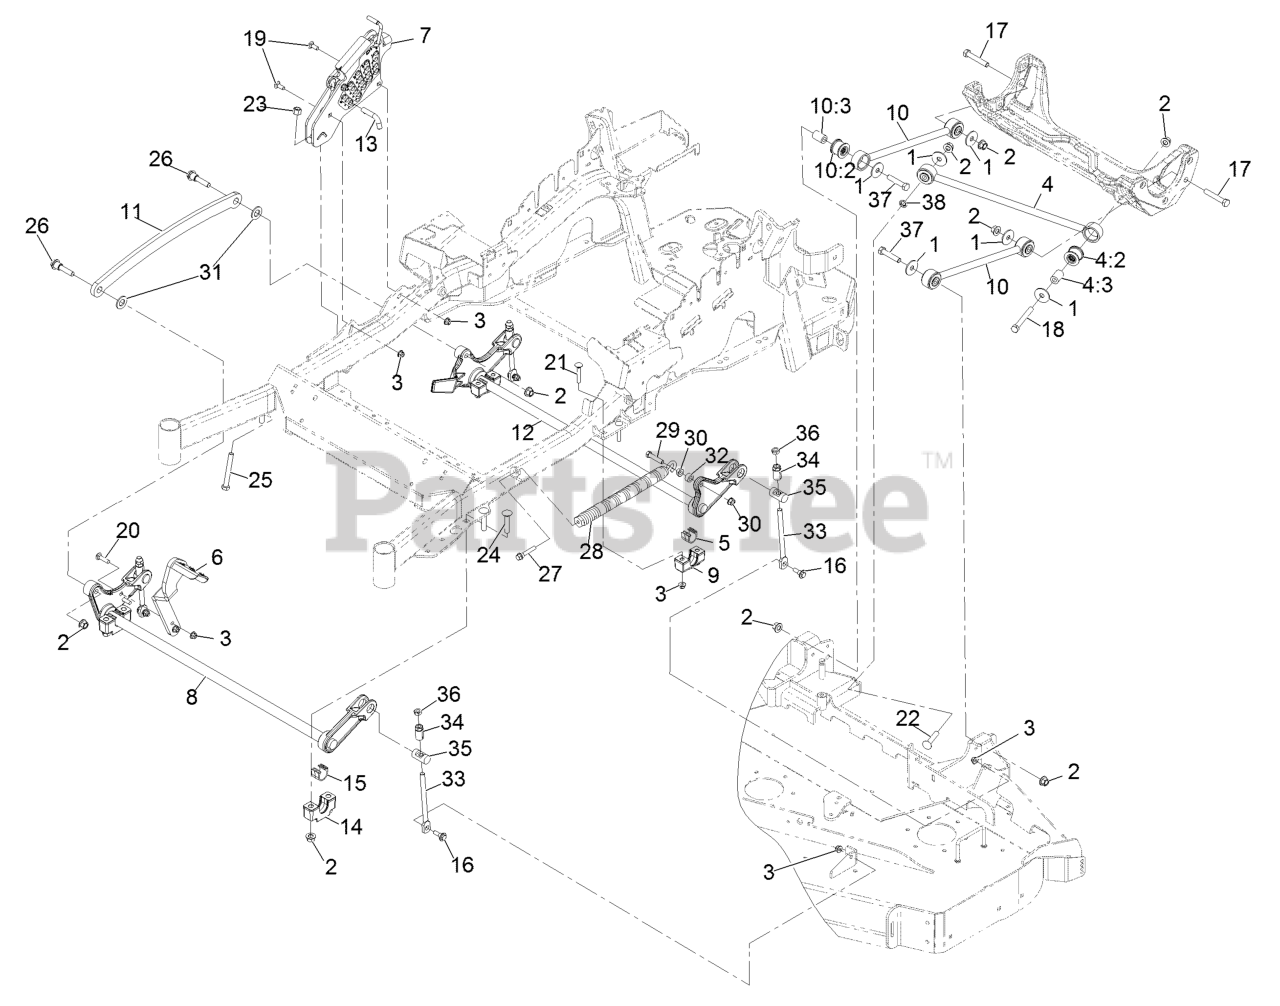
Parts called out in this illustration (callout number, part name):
1	WASHER-THRUST
2	Nut-Lock 1/2-13
3	NUT-HF, NI
4	PANHARD ROD ASM
4:2	BUSHING-SUSPENSION, RUBBER
5	BEARING-CROSS SHAFT, REAR
6	LEVER-FOOT
7	HOC ASM
8	DECKLIFT-FRONT
9	SUPPORT-CROSS SHAFT, BEARING REAR
10	DECK STRUT ASM
10:2	BUSHING-SUSPENSION, RUBBER
11	LINK-LIFT, DECK
12	LIFT-DECK, REAR
13	PIN-HOC
14	SUPPORT-CROSS SHAFT, BEARING
15	BEARING-CROSS SHAFT, FRON
16	SCREW-SHOULDER, HHF
17	SCREW-HH
18	SCREW-HH
19	BOLT-CARR
20	SCREW-CARR
21	Bolt-Carriage 3/8-16 X 2 1/4
22	SCREW-CARR
23	NUT-LOCK, NI
24	Bolt-Carriage 1/2-13 X 2 1/2 Spl Neck
25	BOLT-TAP
26	SCREW-HHF, SHOULDER
27	BOLT-SHOULDER
28	SPRING-EXTENSION
29	SCREW-HH
31	WASHER-FLAT
33	LINK-ADJUSTER, DECK LIFT
34	ADJUSTER-LIFT, DECK
35	TRUNNION
36	NUT-JAM
37	SCREW-HH
38	NUT-PUSH
